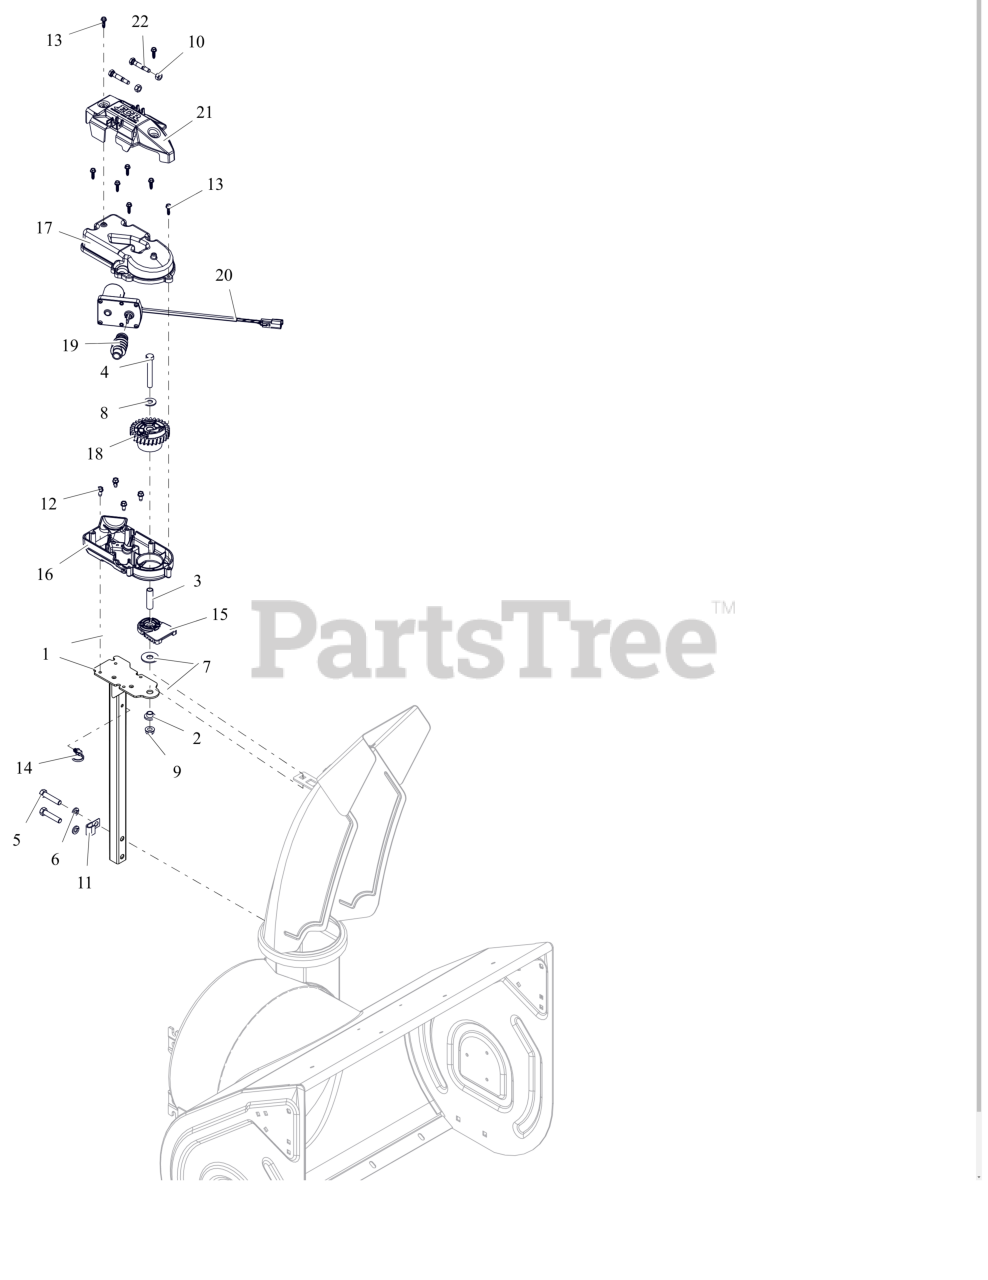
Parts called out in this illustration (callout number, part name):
1	PEDESTAL- ELEC SNOW CHUTE
2	BSHG-FLG .385X.500X.875X.406
3	BSHG-SLV- .391X.500X.1.750
4	BLT, HEX .38-16X2.75 G5 ZCC
5	BLT, HEX .38-16X1.75 G5 ZCC
6	WSHR,LK-REG .375X.094 ZCC
7	WSHR-FLT-NYL .515X1.375X.093
8	WSHR,FLT .438X1.00X.083 ZCC
9	NUT-LK-CTR-FLG .375-16 GF ZCC
10	NUT,LK-CTR .31-18 GA ZCC
11	J-CLAMP
12	SCR-TAP .25-20X.50 HWH ZCC
13	SCR, PLASTITE #12X.75 ZCC
14	CABLE TIE W/ TREE (.25 HOLE)
15	ADAPTOR, CHUTE
16	ENCLOSURE, CHUTE ROTATION (MALE)
17	ENCLOSURE, CHUTE ROATATION (FEMALE)
18	GEAR, HELICAL
19	WORM, DRIVE
20	MOTOR, E-CHUTE
21	COVER- ELECTRIC CHUTE
22	SHEAR BOLT SERVICE ASSEMBLY (INCLUDES NUT)
